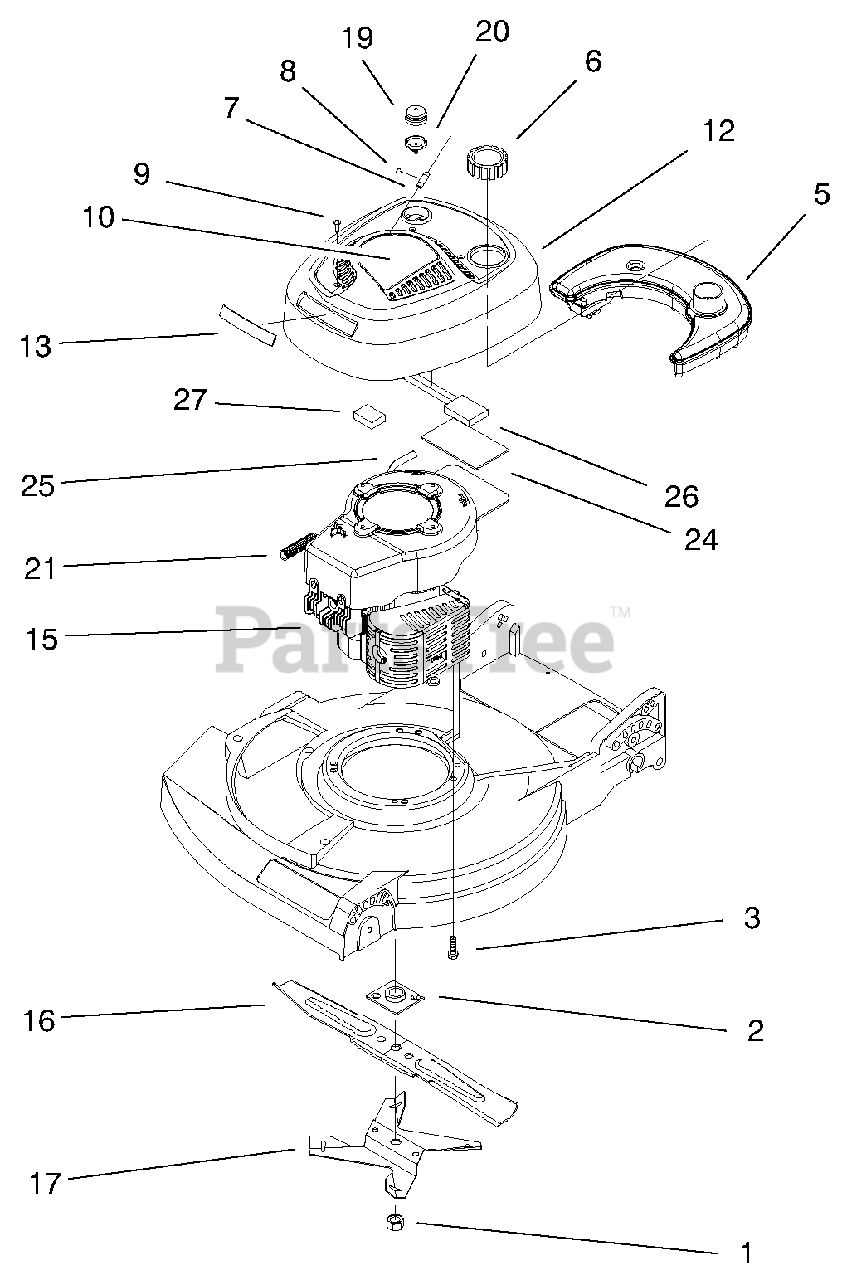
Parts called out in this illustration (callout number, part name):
1	Nut-Blade
2	ASM-Plate & Collar
3	Screw-Sems
5	Gas Tank
6	ASM-Fuel/Oil Cap
7	Rope Stop
8	Staple (Obtain Locally)
9	Screw-Tf Acorn Hd
10	Decal-Recoil
12	ASM-Shroud & Recoil Covr
13	Applique-Shroud
15	Engine ASM Re Cst Hsg Sp
16	Blade-21" Whirl
17	Fan-Mulching
19	Bulb-Primer
20	Body-Primer
21	Spring-Compression
22	Screw-Throttle Cable
23	Nut-Throttle Cable
24	Foam Pad
25	Gas Line
26	Foam Strip
27	Foam Strip
